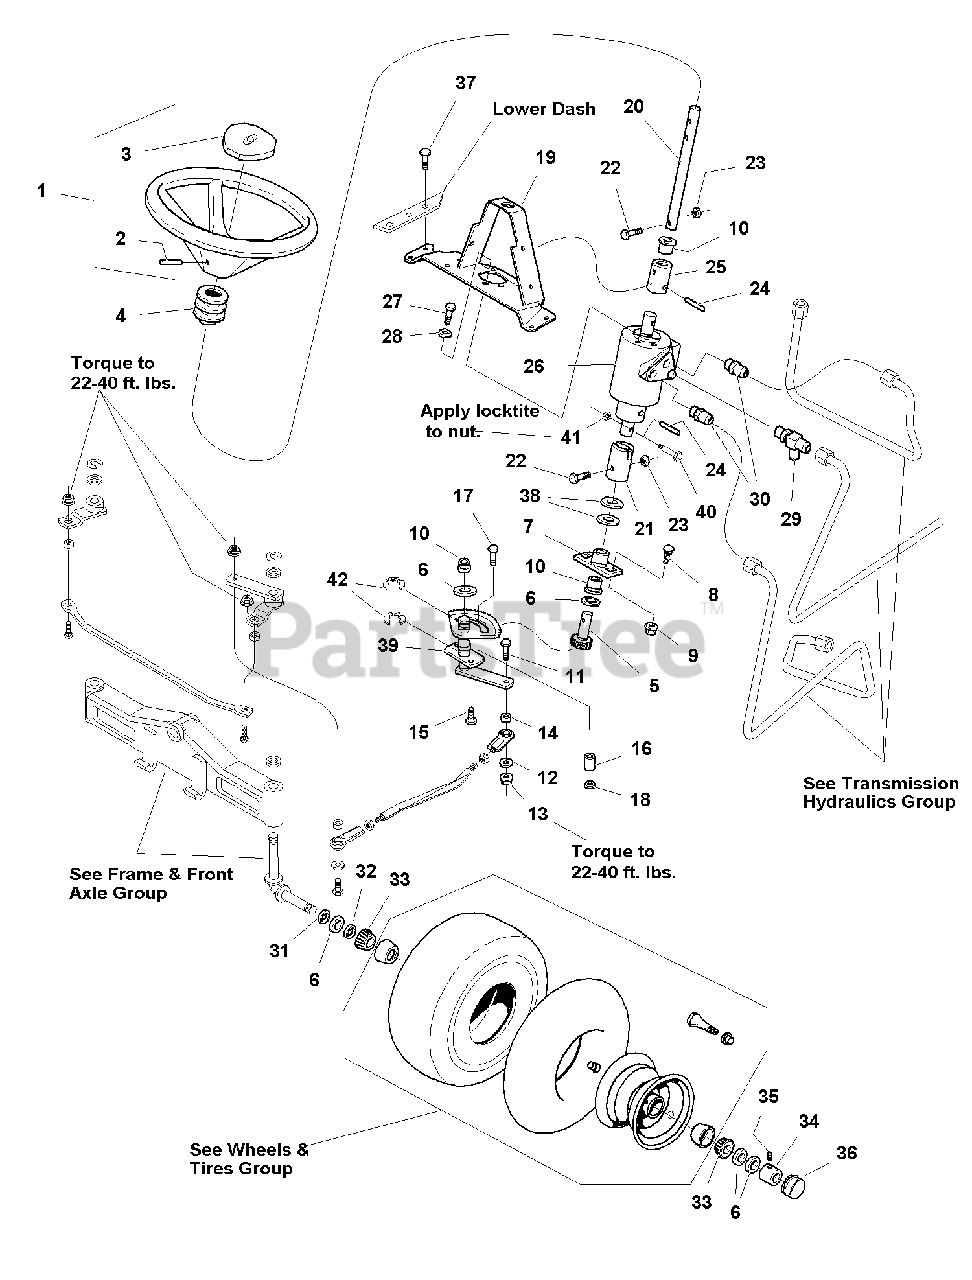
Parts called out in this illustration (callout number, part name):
1	STEERING WHEEL ASSEMBLY (Includes Ref. Nos. 2 & 3)
2	PIN, Spring, 5/8 x 2
3	CAP, Steering Wheel
4	TUBE, Steering
5	SHAFT & PINION ASSEMBLY
6	WASHER, Plain, 3/4
7	PLATE, Steering Mounting
8	CARRIAGE BOLT, 3/8-16 x 1
9	NUT, Hex Flange Whiz Lock, 3/8-16
11	CAPSCREW, Hex Head, 3/8-16 x 1-3/8
12	WASHER, Plain, 3/8
13	NUT, Hex Flange, 2-Way Lock, 3/8-16
15	CAPSCREW, Hex Head, Taptite, 5/16-18 X 1
16	SPACER, Stop
17	CAPSCREW, Hex Head, 5/16-18 x 1-1/2
18	NUT, Hex Nylon Lock, 5/16-18
19	BRACKET & STEERING TOWER ASSEMBLY
20	SHAFT, Upper Steering
21	COUPLING, Lower
22	CAPSCREW, Hex Head 5/16-18 x 2 G5
23	NUT, Hex Nylon Lock, 5/16-18
24	PIN, Spiral (Early Models)(See Service Bulletin 00-5)
25	COUPLING, Upper
26	GENERATOR, Torque
27	CAPSCREW, Hex Head, 5/16-18 X 3/4
28	WASHER, Lock, 5/16
29	FITTING, Hydraulic Tee
30	FITTING, Short Male Tube
33	BEARING, Tapered Roller
34	COLLAR, Set
35	SETSCREW, Square Head, 5/16-18 x 3/8, G8
36	CAP, Hub
37	CAPSCREW, Hex Head, Taptite, 1/4-20 x 1/2
38	WASHER-COUPLER, Steering Gear
39	STEERING GEAR ASSEMBLY
40	BOLT, Shoulder, 5/16 x 1 9/16 with 1/2 Thread (Later Models)
41	NUT, Hex CenterLock, 1/2-20 (Later Models)
42	CLIP RING, 3/4
